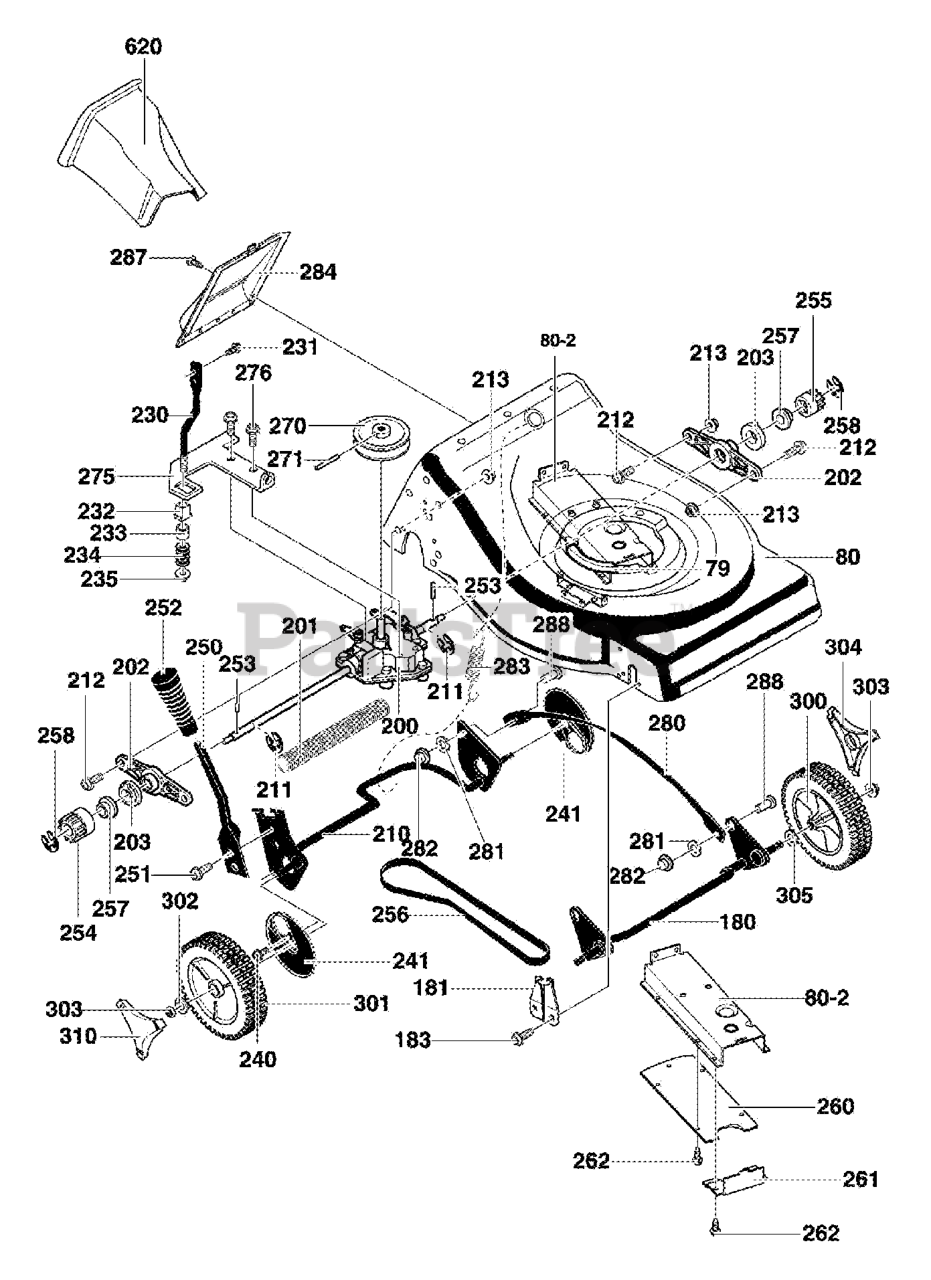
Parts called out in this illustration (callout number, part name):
79	SEAL, FOAM
80	ASSY, FRAME
80-2	GUARD, BELT
180	CROSSBAR, FRONT
181	BUSHING
200	TRANSMISSION
201	SHIELD, AXLE
202	SUPPORT, AXLE
203	BEARING, LIFTER
210	ASSY, CROSSBAR
211	E-RING
212	SCREW
213	NUT
230	SUPPORT, SPRING
232	BUSHING
234	SPRING
235	NUT, 5/16-18
241	DUST COVER
250	LEVER, SPRING
252	KNOB, HEIGHT ADJ
253	PIN, DRIVE
254	GEAR, PINION RIGHT
255	GEAR, PINION LEFT
256	BELT, V
257	WASHER, FLAT
258	E-RING
260	COVER, BELT GUARD
261	COVER, FRONT BELT
270	PULLEY,
271	PIN, SPRING
275	BRACKET, CABLE
280	LINK, LIFTER 21
281	NUT, PUSH ON
282	PUSH ON CAP
283	SPRING, EXTENSION
284	COVER, REAR
288	PIN, CLEVIS
300	TIRE & RIM
301	WHEEL, DRIVE
302	WASHER, FLAT
303	NUT
304	HUB CAP
305	SPRING WASHER
310	HUB CAP
620	PLUG, MULCHER
